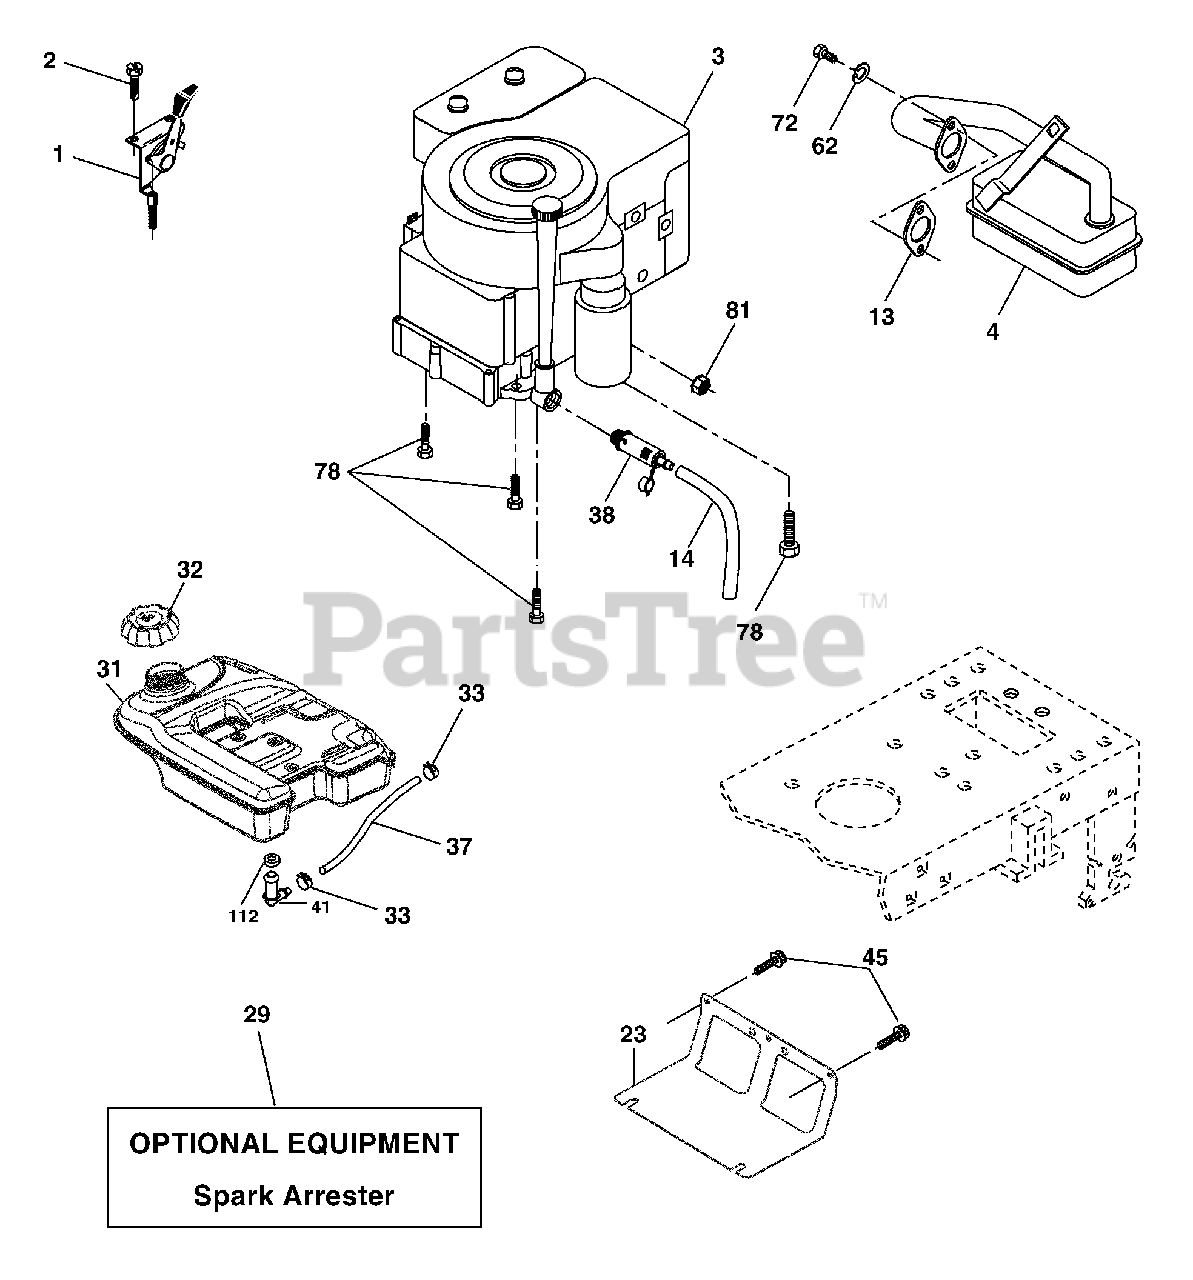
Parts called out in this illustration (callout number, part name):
1	Control Throttle
2	Screw Hwhd Hi-Lo #13-16 x 3/4
4	Muffler
13	Muffler Gasket
14	Tube Drain oil
23	Shield Heat
29	Kit Spark Arrestor (Flat Scrn)
31	Tank Fuel 4.0 Rear
32	Cap Asm Fuel
33	Clamp Hose Black
37	Line Fuel
38	Plug Drain Oil Easy
41	Stem Tank Fuel
45	Screw Hexwsh Thdr 3/8-16 x 3/4
62	Washer Split
72	Screw 5/16-18 x 3/4
78	Screw 3/8-16 x 1-1/4
81	Nut Keps Hex 1/4-20 unc
112	Bushing
